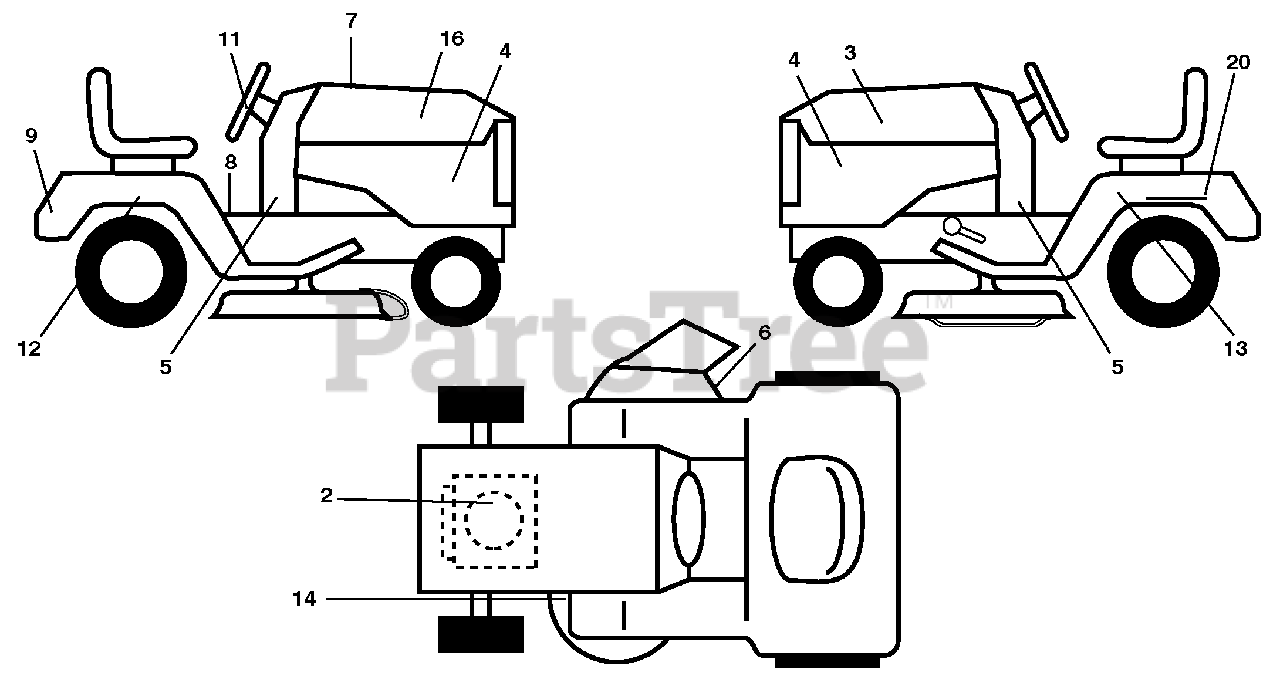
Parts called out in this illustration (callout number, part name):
2	Decal Eng. H.P.
3	Decal Hood LH
4	Decal Side Panel Logo
5	Decal Lwr Dash
6	Decal Warning, Keep Hand Away
7	Decal Replacement Parts
8	Decal Fender Warn S/F
9	Decal Fender Logo
11	Decal Ins Strg Whl
12	Decal Fend SD RH
13	Decal Fend SD LH
14	Decal V-Belt Schematic
16	Decal Hood RH
20	Decal Bat Dan/Psn
20	Pad Footrest LH
20	Pad Footrest RH
20	Manual Operator's (Eng/French)
20	Manual Parts (Eng/French)
